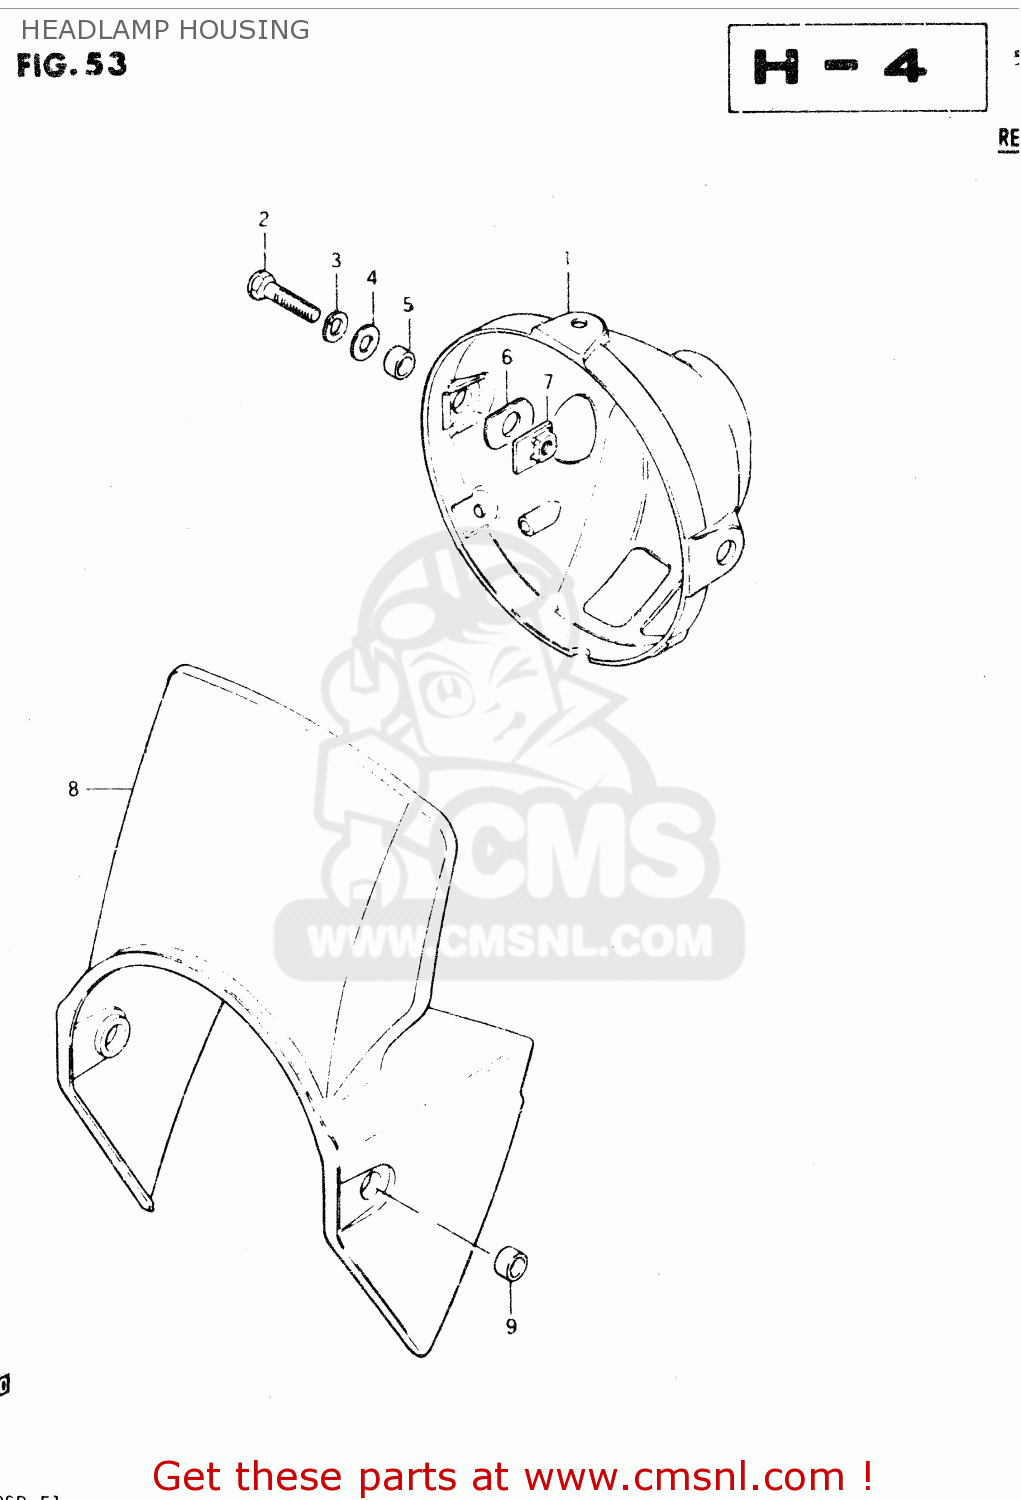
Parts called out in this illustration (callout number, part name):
1	HOUSING,HEAD LAMP
2	BOLT
3	LOCK WASHER
4	WASHER
5	SPACER (8.8X12X7)
6	CUSHION
7	PLATE,HEADLAMP HOUSING
8	COVER, HEADLAMP (BLUE)
9	SPACER (8.8X12X7)
